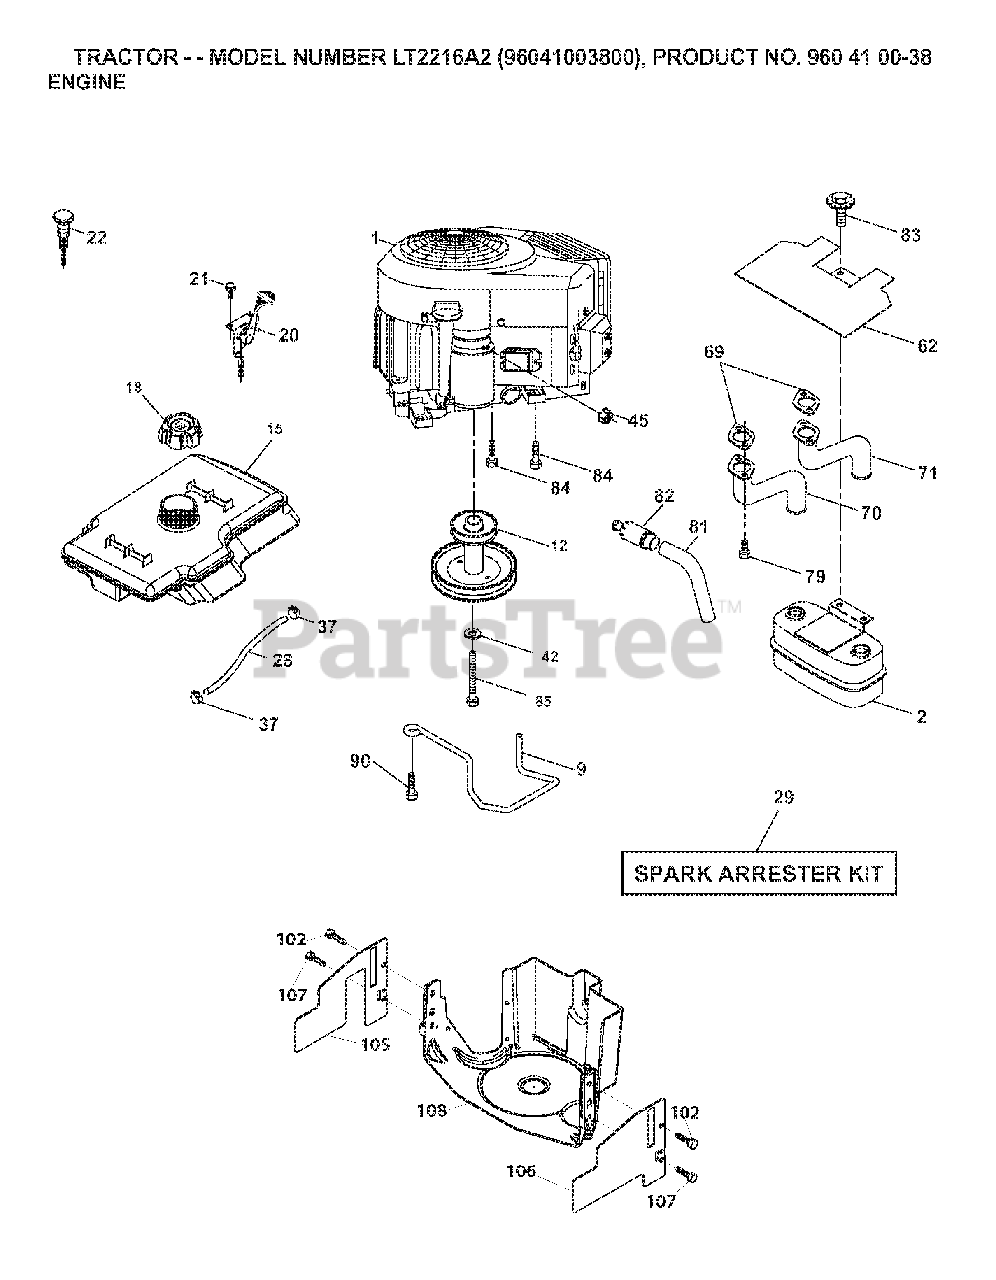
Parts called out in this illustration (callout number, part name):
2	MUFFLER.TWIN.CYL.LOW.TONE
9	KEEPER.BELT.ENGINE.4.2
12	PULLY ENGINE
18	CAP.ASM.FUEL.TANK.3"BL
20	THROTTLE CABLE
21	SCREW
22	CONTROL CHOKE
29	ARRESTER SPARK (OPTIONAL)
37	HOSE CLAMP
42	LOCKWASHER
45	NUT
62	RP SHIELD HEAT MUFFLER
69	REPL BY 532 27 22-93
70	TUBE MANIFOLD LH
71	EXHAUST TUBE RH
79	SCREW.SOCKET.HEAD.5/16-18
81	TUBE, DRAIN OIL ASM.
82	PLUG DRAIN OIL EASY
83	BOLT, 5/16-18 X 1 3/4
84	SCREW.3/8-16
85	BOLT HEX 7/16-20X4-1/4"
90	SCREW 3/8-16X1
102	SCREW
107	SCREW.1/4-20X5/8
